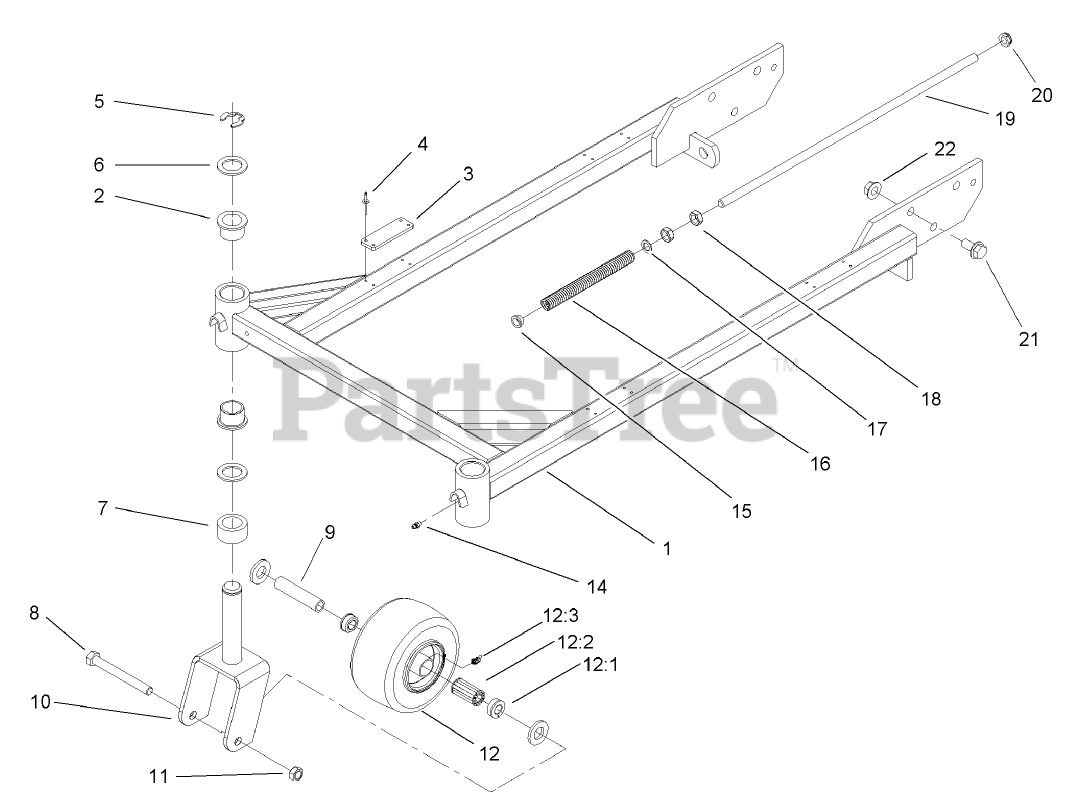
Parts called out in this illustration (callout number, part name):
1	Frame-Carrier
2	BUSHING
3	PAD-RUBBER
4	RIVET
5	RING-RETAINING
6	WASHER-THRUST
7	SPACER-CASTOR
8	SCREW-HH
9	SPANNER
10	FORK-CASTER ASM
11	NUT-HEX
12	CASTER WHEEL ASM
12:1	BEARING-OUTSIDE
12:2	BEARING-ROLLER
12:3	FITTING-LUBE, 45 DEG
13	SPACER-WHEEL
14	FITTING-GREASE
15	BUSHING-FLANGE
16	SPRING
17	WASHER
18	NUT-JAM
19	SHAFT-ADJUSTING
20	NUT-LOCK, NI
21	SCREW-HHF
22	NUT-HF
